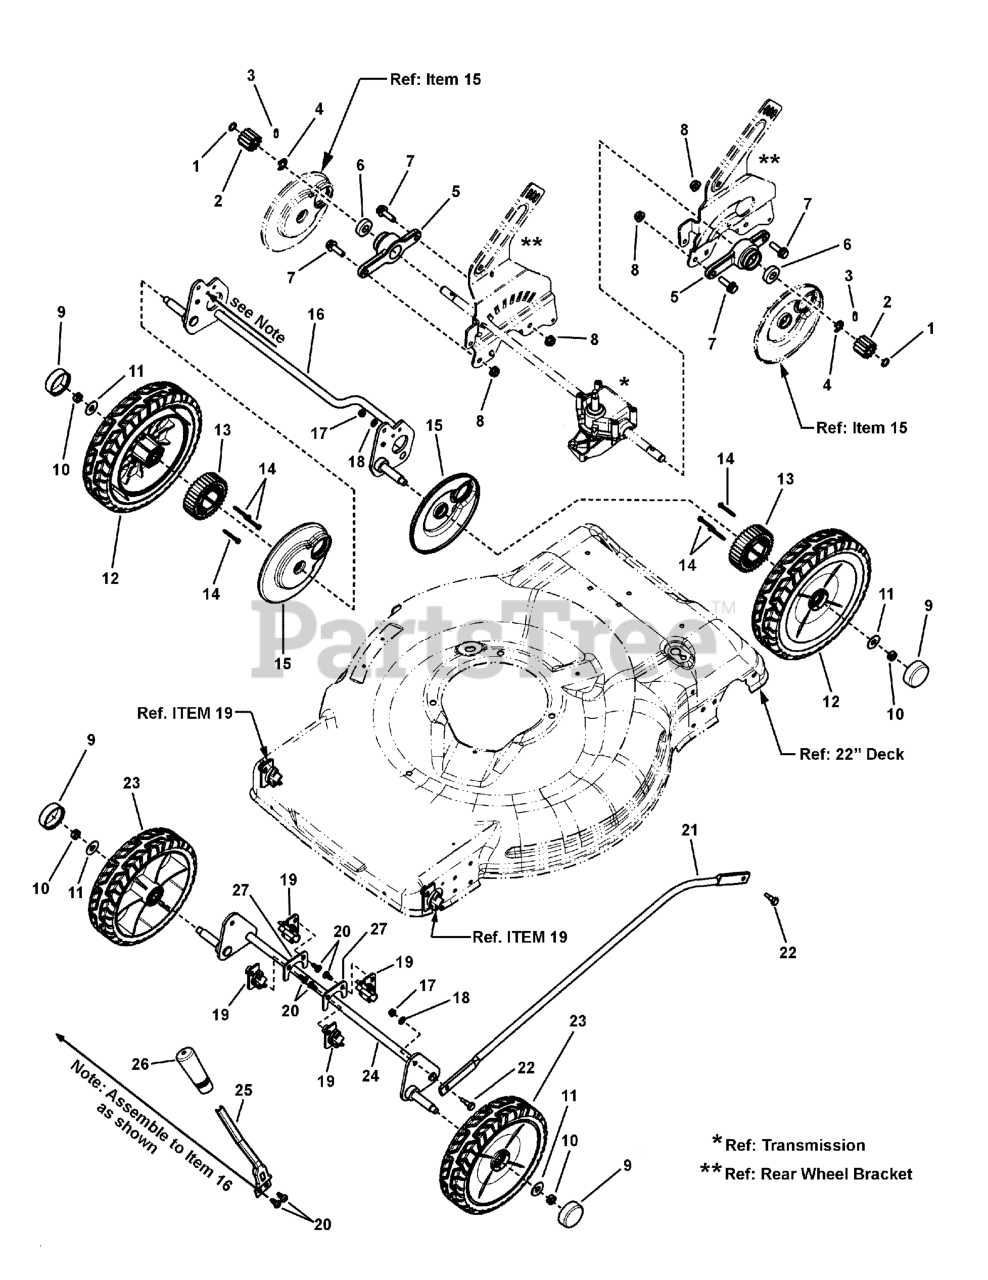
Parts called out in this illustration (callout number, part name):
1	RETAINING RING
2	GEAR, PINION
3	PIN, AXLE
4	RETAINING RING
5	HOLDER, BEARING, RWD
6	BEARING, Ball
7	HFLB, 5/16-18 X 1 YZ
8	FLN, 5/16-18 YZ
9	HUBCAP, ROUND, JD YELLOW
10	HCLN, JAM - 3/8-16 YZ
11	WASHER, FLAT, 1" OD X .387 ID
12	ASSY, WHEEL, W/BEARING 9" JD TRD, JD YELLOW
13	GEAR, EXTERNAL WHEEL
14	HWST, #8 X 1-1/4, HI-LO
15	SHIELD, DUST, 21" WBM, RD
16	WELDMENT, REAR CROSSBAR, RWD
17	HLN, 10-24 UNC-2B W/NYLON INSERT
18	FLW, .219 X .500 X .049 BL
19	BUSHING, BEARING, RWD
20	TORX ST, 1/4-20 X .550
21	ROD, LIFTER LINK, WBM
22	BOLT, SHOULDER, 1/4 X .375, YZ
23	ASSY, WHEEL, 8X2 IDLE, JD TRD, BB, JD YELLOW
24	WELDMENT, FRONT CROSSBAR, RD
25	LEVER, SPRING, HOC
26	GRIP, HOC JD YELLOW
27	PLATE, SUPPORT, FRONT BUSHING
